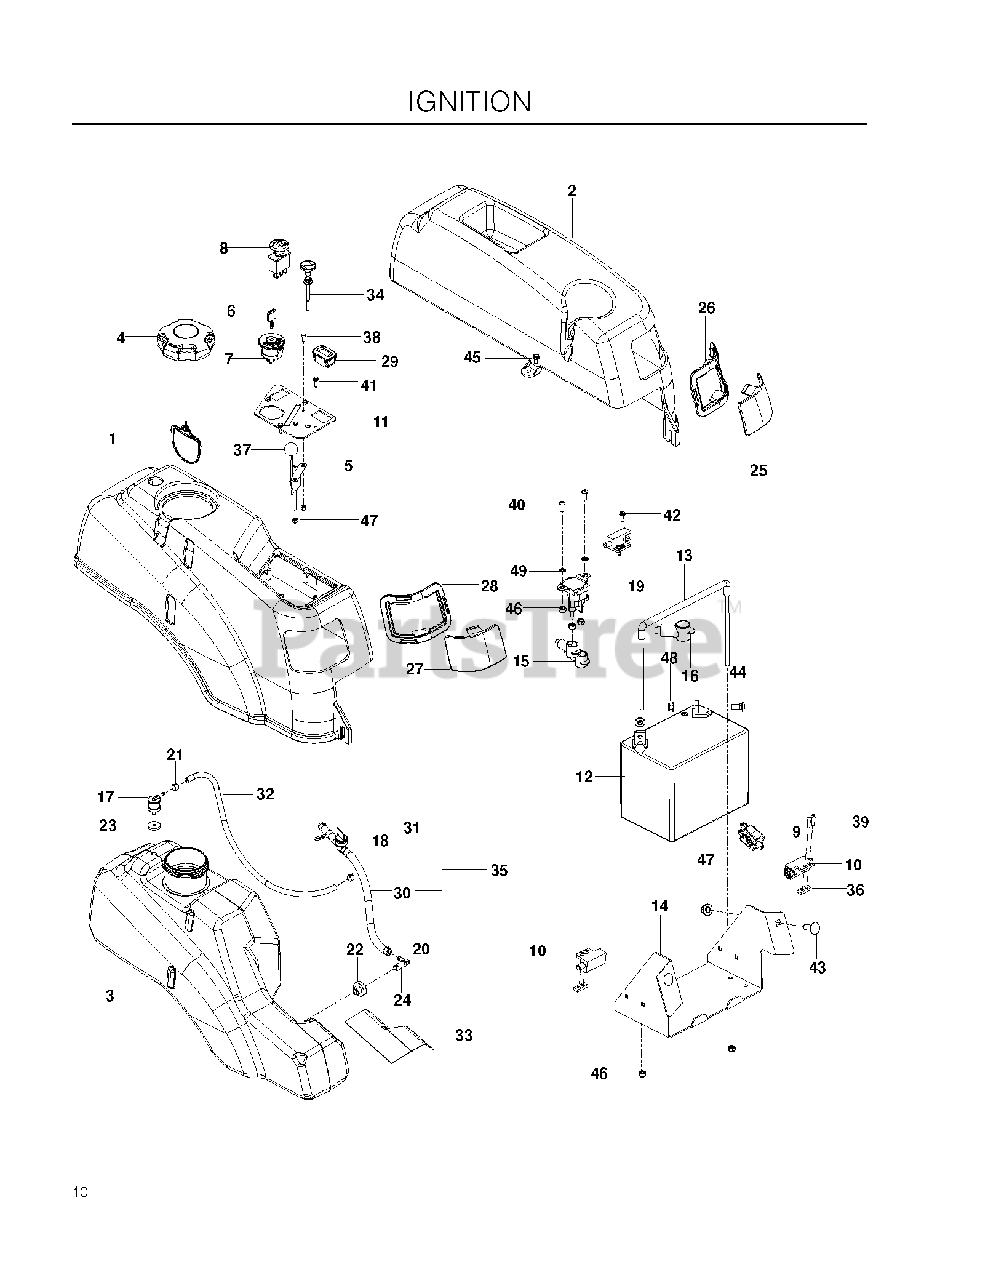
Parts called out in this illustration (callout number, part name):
1	FENDER RT, BLACK
2	FENDER, LT
3	TANK.FUEL.RT.EPA
4	CAP, FUEL
5	THROTTLE CONTROL W/BALL KNOB
6	KEY
7	RP IGNITION SWITCH
8	RP SWITCH, BLADE
9	SWITCH, BRAKE 3P
10	SWITCH, INTERLOCK
11	CONSOLE.PLATE.BLACK
12	BATTERY, 12 V 330 AMP
13	BATTERY TIE DOWN ASSEMBLY
14	BOX, BATTERY, BLACK
15	TERMINAL COVER-SM
17	VALVE.FUEL.CHECK
18	FUEL VALVE
20	HOSE CLAMP
21	CLAMP, HOSE
22	RUBBER GROMMET
23	GROMMET, CHECK VALVE
24	STEM, FUEL TANK
25	LENS, COLORED LEFT
26	LEFT HEADLIGHT RIM GREY
27	LENS, COLORED RIGHT
28	RT HEADLIGHT RIM GREY
29	HOUR METER
30	GAS LINE 10"
31	FUEL LINE 3"
32	HOSE, FUEL, 3/16" X 17-1/4"
33	SHIELD, HEAT
34	CHOKE CABLE
35	FUEL LINE ASSY
36	TAPPED PLATE
37	KNOB.ROUND.BALL.BLACK
38	HCS #10-24 X 1/2
39	SCR #10-24 X .75 SKT HD BLK
40	SCR 1/4-20 X 5/8 BTN SKT HD ZD
41	SCR #10-12X3/4 HEX WAS HD ZD
42	SCREW #10 X 1/2 SELF TAPPING
43	RHSNB 3/8C X 1
44	BOLT 5/16C X 3/4" CARRIAGE
45	BOLT 1/4-20 X 1/2 HWST
46	RP_NUT 1/4-20 NYLOC
47	NUT 10-24 NYLOC
48	5/16-18 NYLOC FLANGE NUT
49	WASHER 1/4 INT TOOTH
